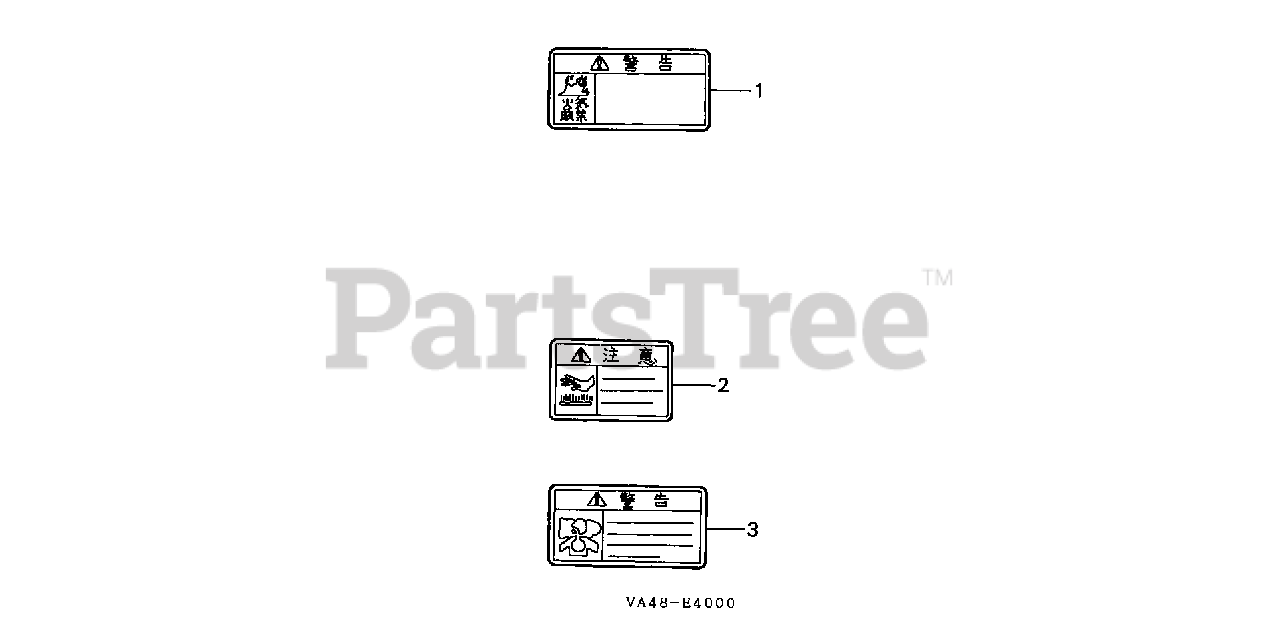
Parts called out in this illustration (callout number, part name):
1	MARK, FUEL WARNING Use from Engine SN 1011058.
2	MARK, HEAT CAUTION Use from Engine SN 1011058.
3	MARK, EX. GAS WARNING Use from Engine SN 1011058.
